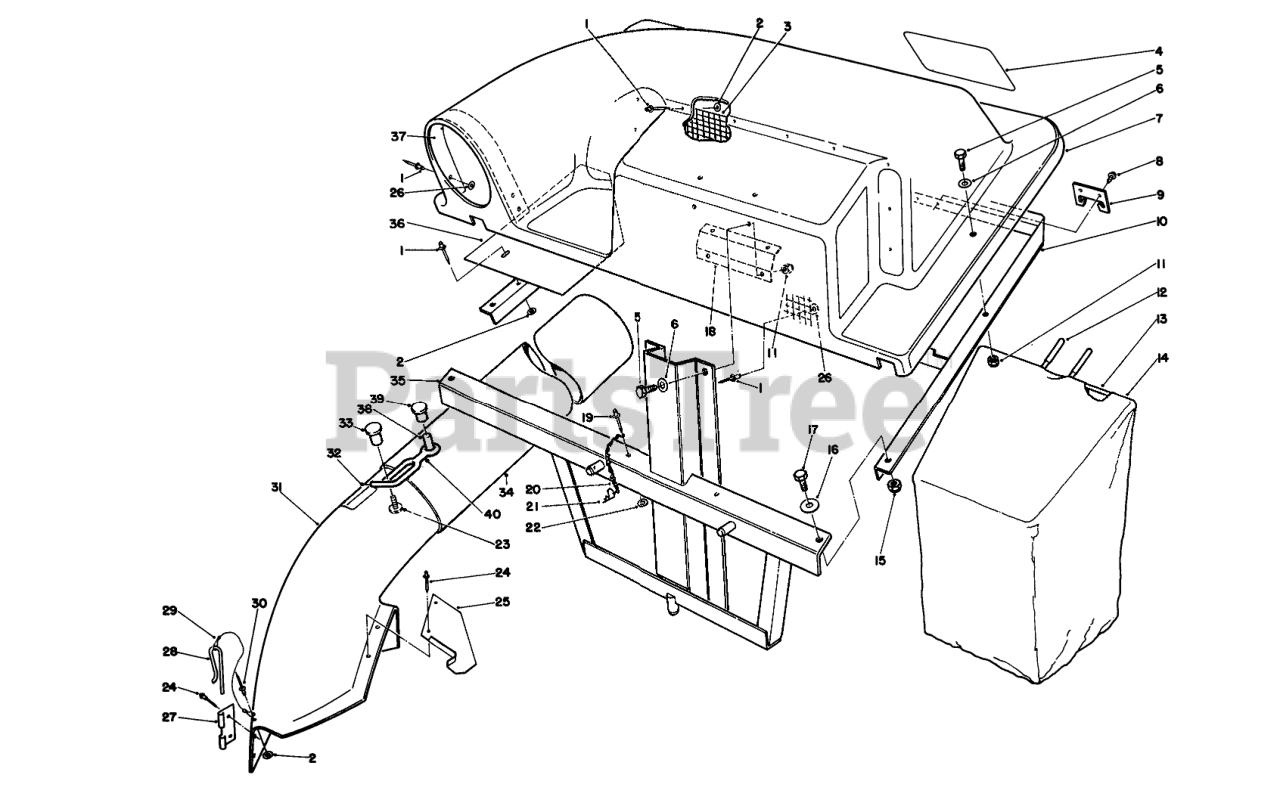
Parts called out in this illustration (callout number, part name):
1	RIVET-POP
2	WASHER-PLAIN
3	SCREEN
4	DECAL-BAGGER, TWIN
5	SCREW-HH
6	WASHER-PLAIN
7	COVER-BAGGER, TWIN
8	SCREW-HWH
9	BRACKET-FRAME, BAG
10	Cover-Frame
11	NUT-LOCK, NI
12	GRIP-HANDLE, BAG
13	Frame-Bag
15	NUT-LOCK, NI
16	WASHER-FLAT
17	SCREW-HH
18	Plate-Backup
20	10 LINK CHAIN W/O HOOK
21	PIN-HAIR
22	WASHER-BACK
23	Screw
24	RIVET-BLIND
25	CHUTE SUPT BRKT
26	WASHER-FLAT
27	BRACKET-MOUNTING, CHUTE
28	PIN-LOCKING, CHUTE
29	LANYARD
30	RIVET-BLIND
31	Assembly-Chute (Incl. Ref. #24-30 & 32)
32	DECAL-DANGER
34	Duct
35	Frame-Mounting
36	Baffle
37	Support Inlet
38	SPACER-INTERLOCK
39	FASTENER-PANEL
40	RETAINER-DUCT
